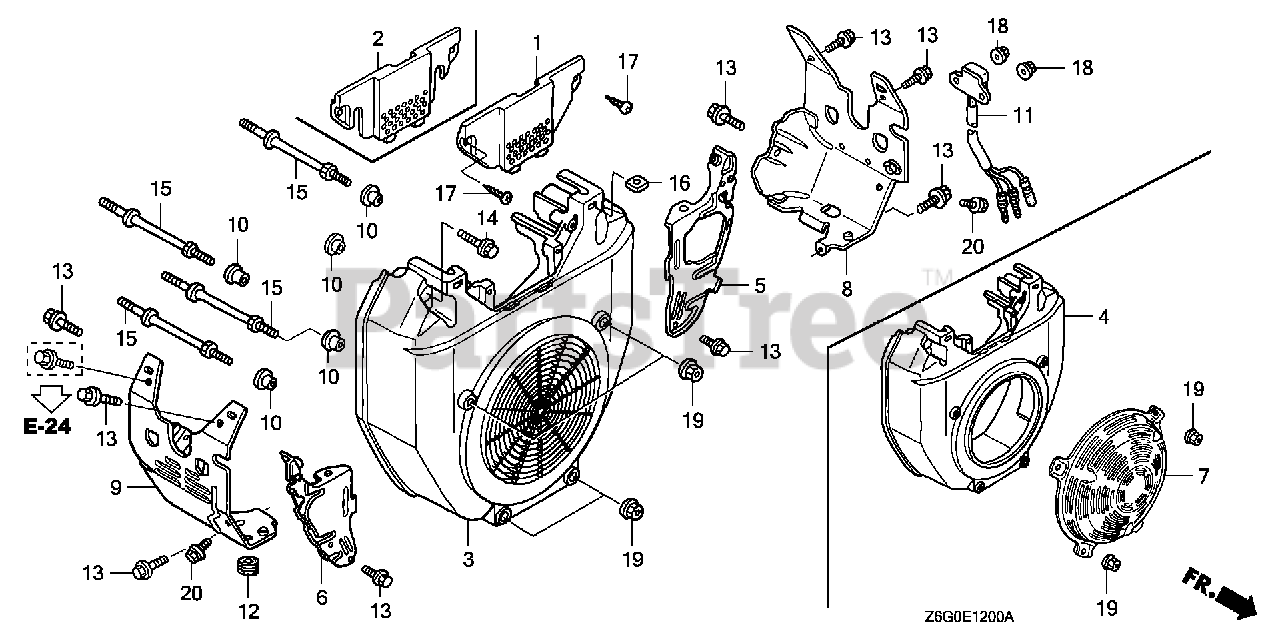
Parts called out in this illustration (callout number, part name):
2	COVER, FUEL PUMP (MANUAL CONTROL)
3	COVER, FAN *R280* (POWER RED)
5	PLATE, SIDE (L. SIDE)
6	PLATE, SIDE (R. SIDE)
8	SHROUD (OIL ALERT) (L. SIDE)
9	SHROUD (R. SIDE)
10	COLLAR B, TAILLIGHT
11	ALERT UNIT, OIL
12	RUBBER, RR. FENDER CUSHION
13	BOLT, FLANGE (6X12) (CT200)
14	BOLT, FLANGE (6X23) (CT200)
15	BOLT, STUD (6X71)
16	NUT, SQUARE (5MM)
17	SCREW, TAPPING (5X20)
18	NUT, FLANGE (5MM)
19	NUT, FLANGE (6MM)
20	BOLT, FLANGE (6X8)
